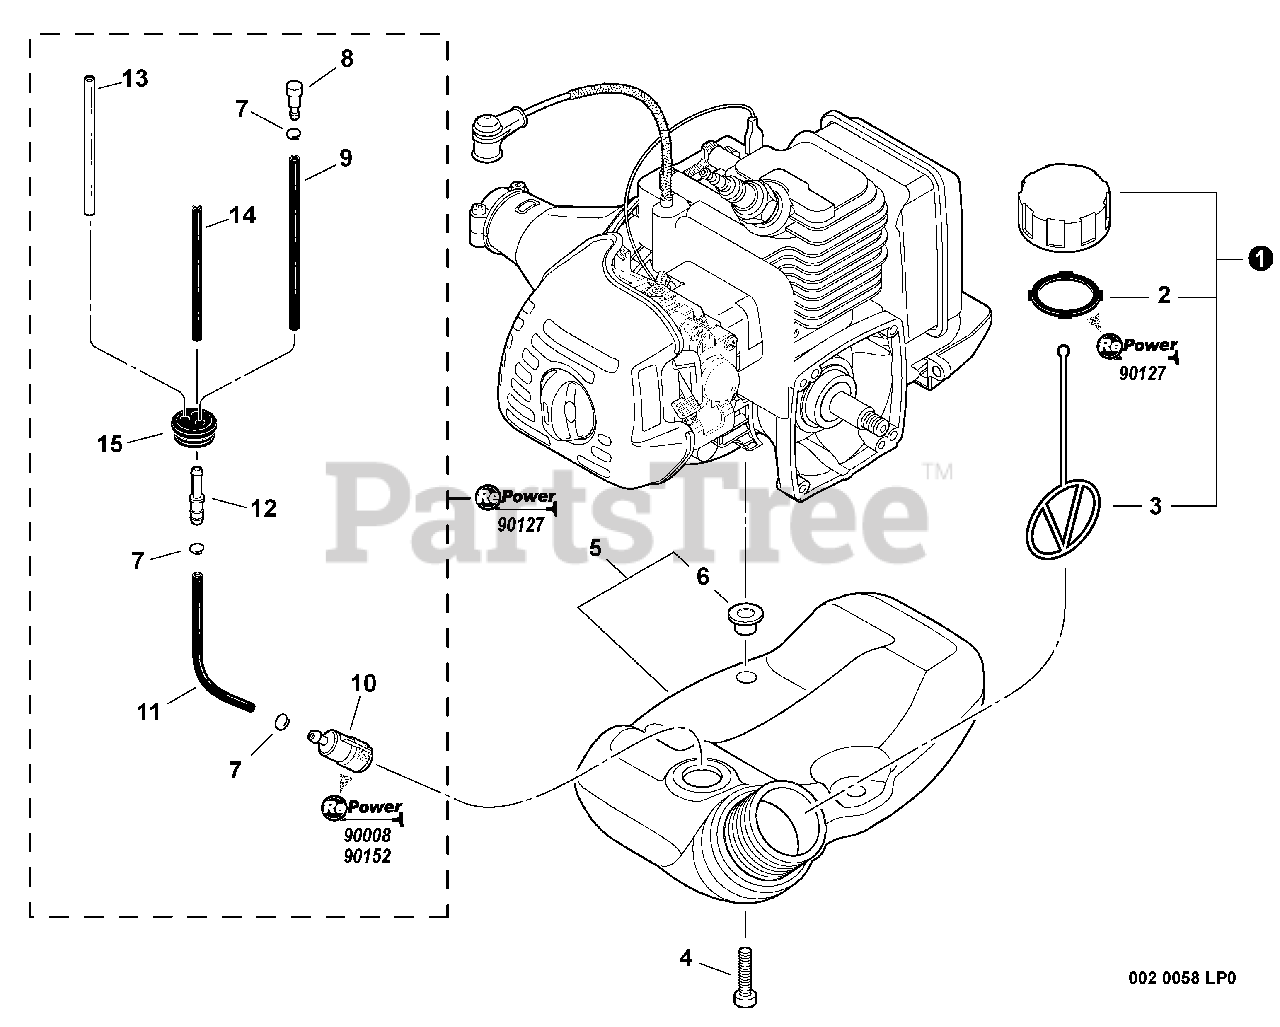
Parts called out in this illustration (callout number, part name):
1	CAP ASSY - ORANGE
2	GASKET, CAP
3	CONNECTOR, CAP
4	SCREW - 5X20
5	FUEL TANK ASSY
6	COLLAR - 5
7	CLIP - 6
8	VENT, FUEL TANK
9	PIPE - 3X5X90 -- BLACK
10	FILTER, FUEL
11	PIPE - 3X5X130 -- BLACK
12	CONNECTOR, PIPE
13	PIPE - 3X6X80 -- CLEAR
14	PIPE - 3X5X74 -- BLACK
16	RePower FUEL SYSTEM KIT
17	RePower TUNE-UP KIT
18	RePower FILTER KIT
19	RePower BULK PIPE - 25 FEET
20	RePower BULK PIPE - 25 FEET
